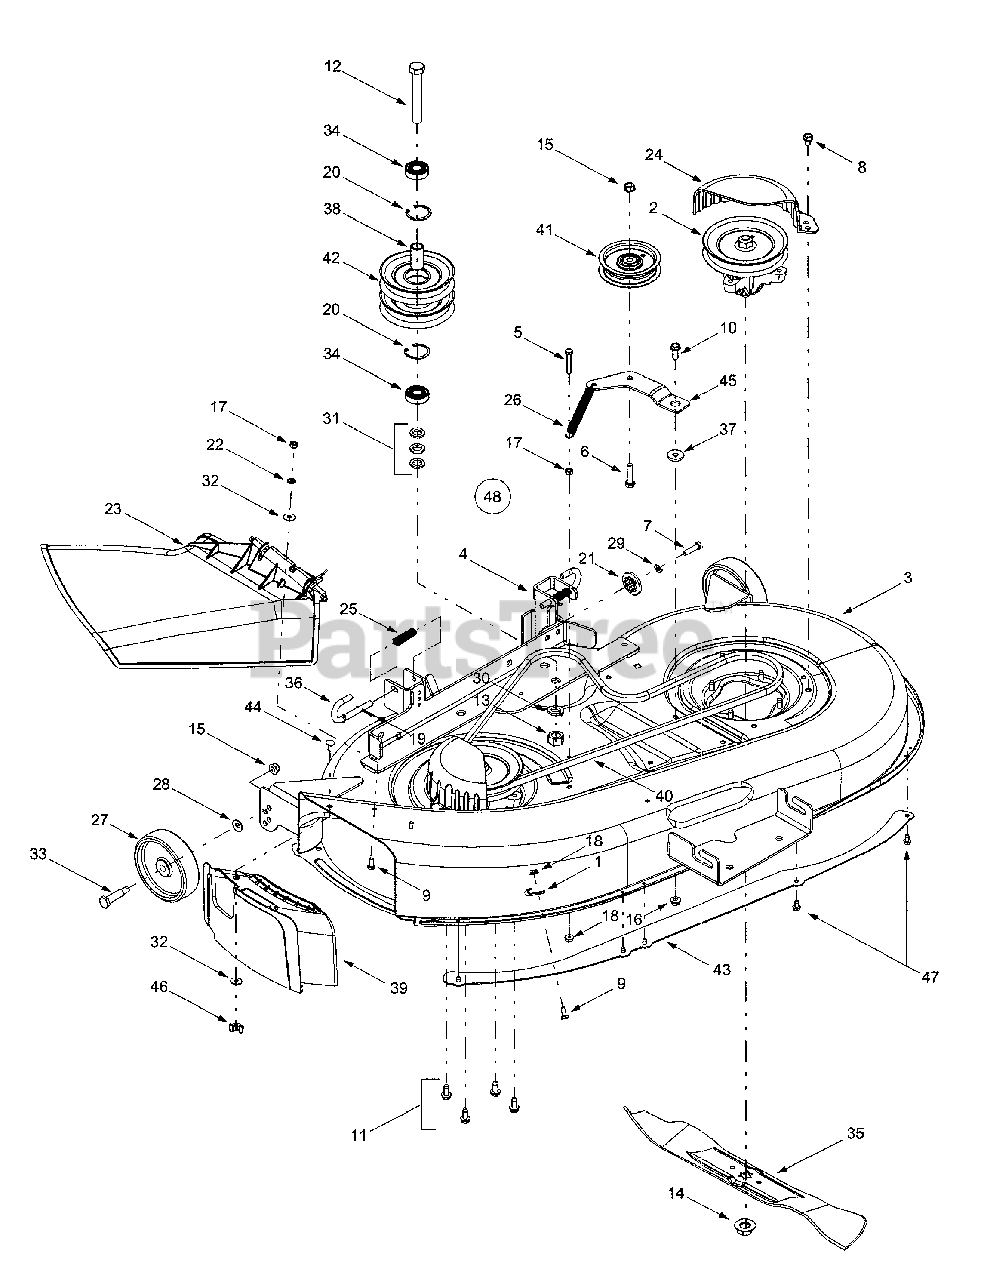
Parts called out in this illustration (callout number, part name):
1	Retainer Hook
2	Spindle Assembly, 5.75 Dia. w/ Fitting
5	Hex Cap Screw, 1/4-20 x 1.75
6	Hex Cap Screw, 1/4-20 x 1.5
7	Hex Cap Screw, 5/16-18 x 1.25
8	Self-tapping Screw, 5/16-18 x .625
9	Hex Cap Screw, 1/4-20 x .62
10	Hex Head Washer Screw, 5/16-18 x .875
11	Self-tapping Screw, 5/16-18 x .75
12	Hex Cap Screw, 5/8-18 x .875
13	Hex Nut, 5/8-18
14	Hex Flange Nut, 5/8-18
15	Flange Lock Nut, 3/8-16
16	Flange Lock Nut, 5/16-18
17	Hex Nut, 1/4-20
18	Hex Flange Lock Nut, 1/4-20
19	Cotter Pin, 1/8 x 1.25
20	Internal Snap Ring
21	Deck Adjustment Gear
22	Push Nut. .25 x .5
23	Side Discharge Chute Assembly
24	Belt Cover
25	Compression Spring, .406 x .531 x 1.75
26	Extension Spring, .50 x 4.74
27	Deck Wheel, 5 x 1.38
28	Bell Washer, .401 x .87 x .063
29	Lock Washer, 5/16
30	Lock Washer, 5/8
31	Flat Washer, .64 x 1.0 x .12
32	Bell Washer, .265 x .75 x .062
33	Shoulder Screw, .498 x 1.53
34	Bearing, .625 x 1.574 x .470
35	Three-in-one Blade, Star Center, 21.23"
36	Deck Release Pin
37	Shoulder Spacer, .625 x .324
38	Spacer, .635 x .88 x 1.72
39	Mulch Plug
40	Deck Belt
41	Idler Pulley, 3.5
42	Double Pulley, 5.0
44	Carriage Screw, , 1/4-20 x .62
46	Wing Nut, 1/4-20
47	Self-tapping Screw, 1/4-20 x.5
